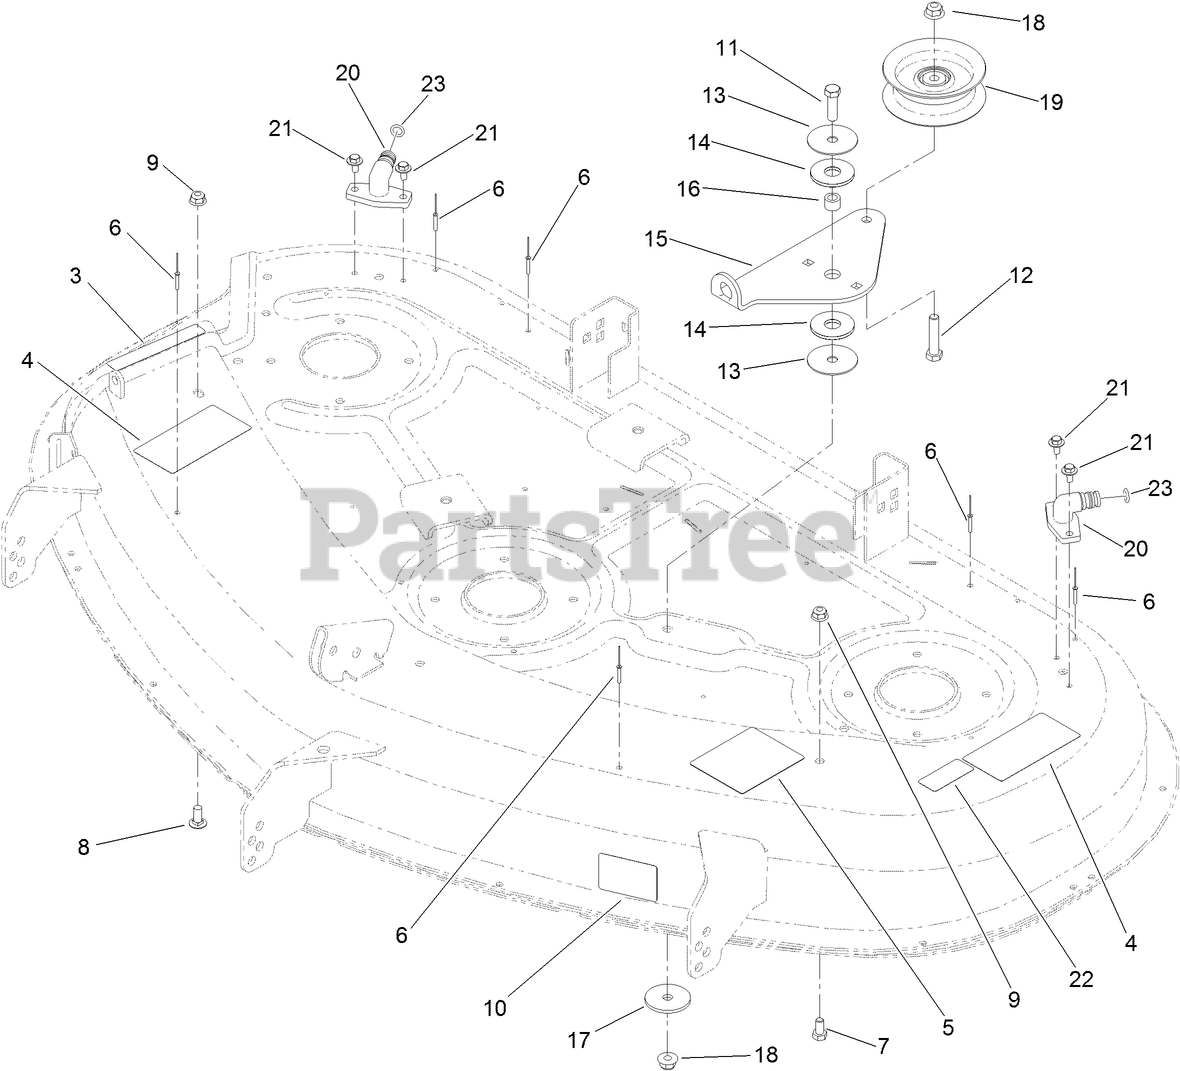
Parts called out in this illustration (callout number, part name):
3	DECAL-DANGER
4	DECAL-DANGER, DECK
5	DECAL-ROUTING, BELT
6	RIVET-BLIND
7	SCREW-HH
8	SCREW-CARR
9	NUT-HF, NI
10	DECAL-SCALP, ANTI
11	SCREW-HH
12	SCREW-HH
13	WASHER
14	WASHER-FRICTION, COMPOSITE
15	ARM-IDLER
16	SPACER
17	WASHER-REBOUND
18	NUT-HF, NI
19	PULLEY-IDLER, FLAT
20	FITTING-WASHOUT
21	SCREW-HHFTF
22	SERVICE DECAL
23	O-ring
